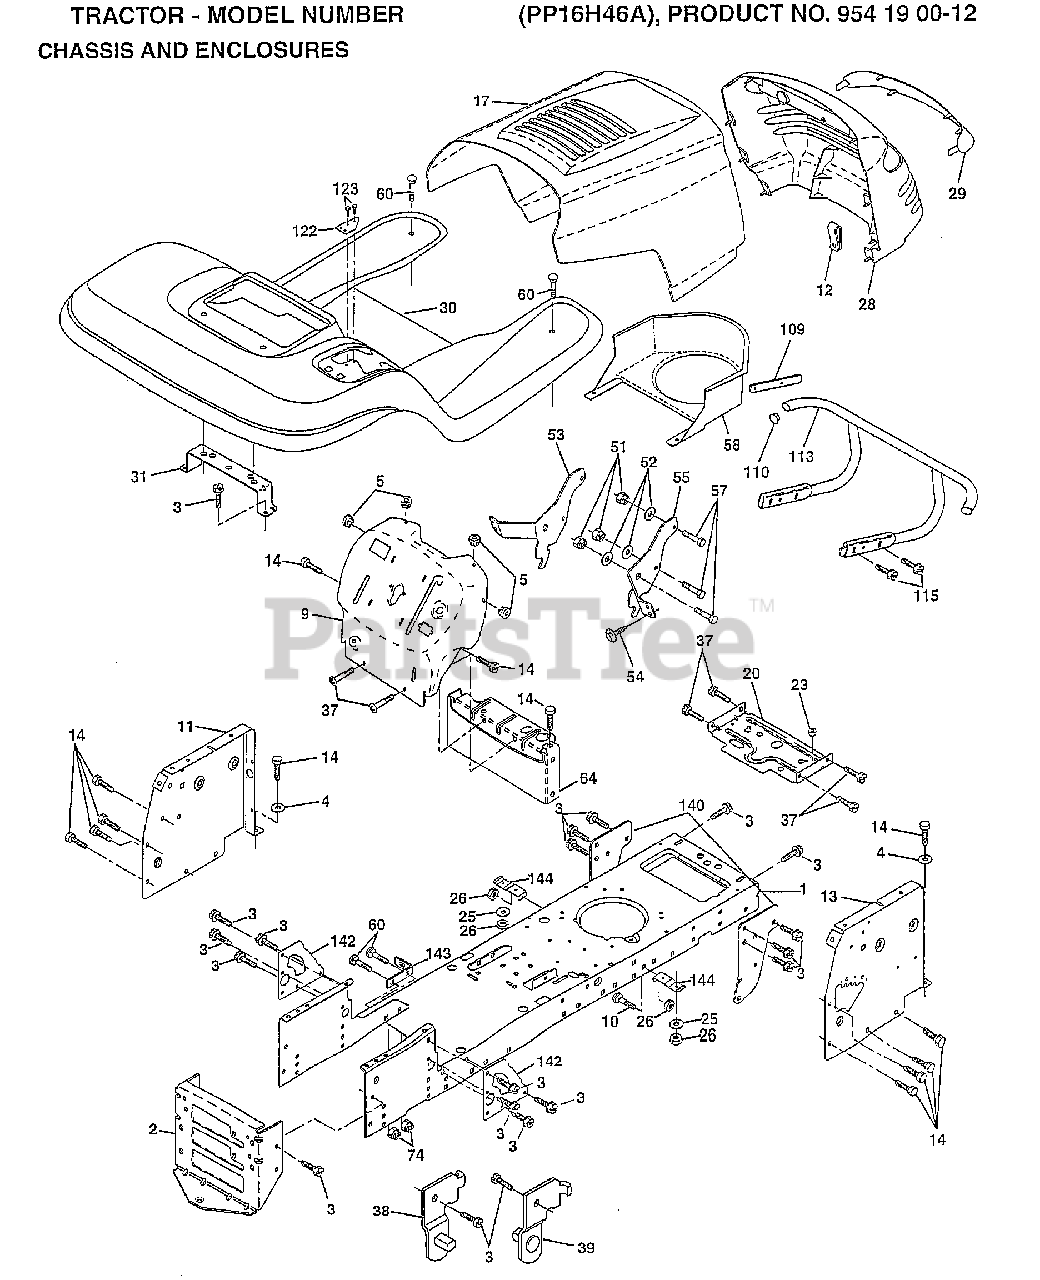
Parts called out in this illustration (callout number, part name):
3	SCREW
4	WASHER
5	BUMPER-HOOD/DASH
11	"PANEL-DASH,LH"
12	CLIP.TINNERMAN
13	"PANEL-DASH,RH"
14	SCREW LT
20	"PLATE-MTG,BATT/FU"
25	WASHER
26	NUT
28	GRILLE-MS428
29	LENS GRILLE
30	FENDER/FOOTREST
31	BRACKET SUPT FEND
37	SCREW LT
38	BRACKET ASM LH
39	BRACKET ASM RH
51	NUT
52	WASHER
53	BRACKET.GRILLE.LH
55	BRACKET.GRILLE.RH
58	AIR DUCT
60	BOLT
64	DASH-LOWER
109	BRACKET.EXT.BUMP.
110	PLUG.PLASTIC
113	BUMPER.ASM
115	SCREW
122	"BRKT SHIFT,LT"
123	"SCREW-TT,10-32 FL"
140	BRKT SUSPENSION
142	PLATE.REINFORCEMT
143	"BRKT-S'BAR,CHASSI"
144	BRKT-FOOTREST
